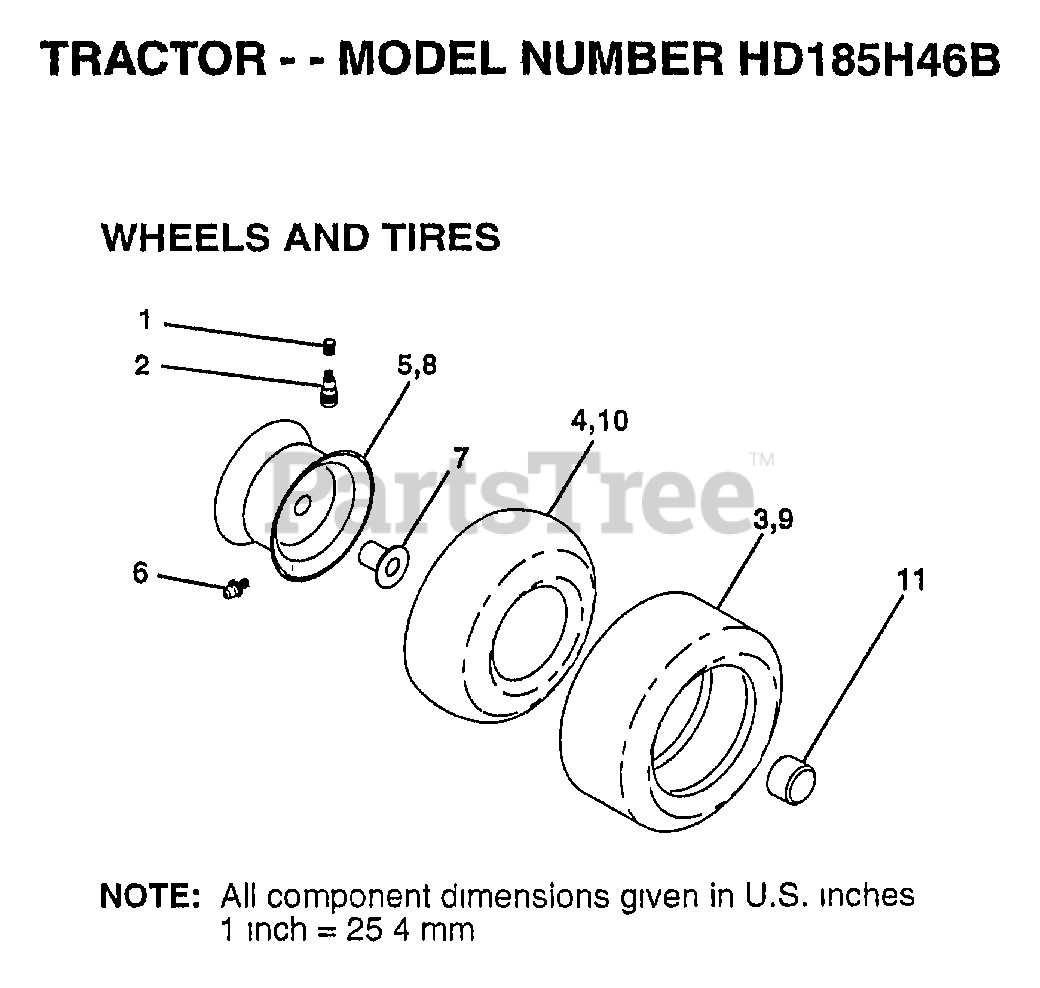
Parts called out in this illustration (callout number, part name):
1	VALVE CAP
2	VALVE STEM LT
4	TUBE.5.3/4.5/6
5	"RIM ASM 8"" FRT"
6	FITTING LT
7	"FLANGE, BEARING"
8	RIM.REAR.
10	TUBE.23X8/10-12
11	HUB CAP
